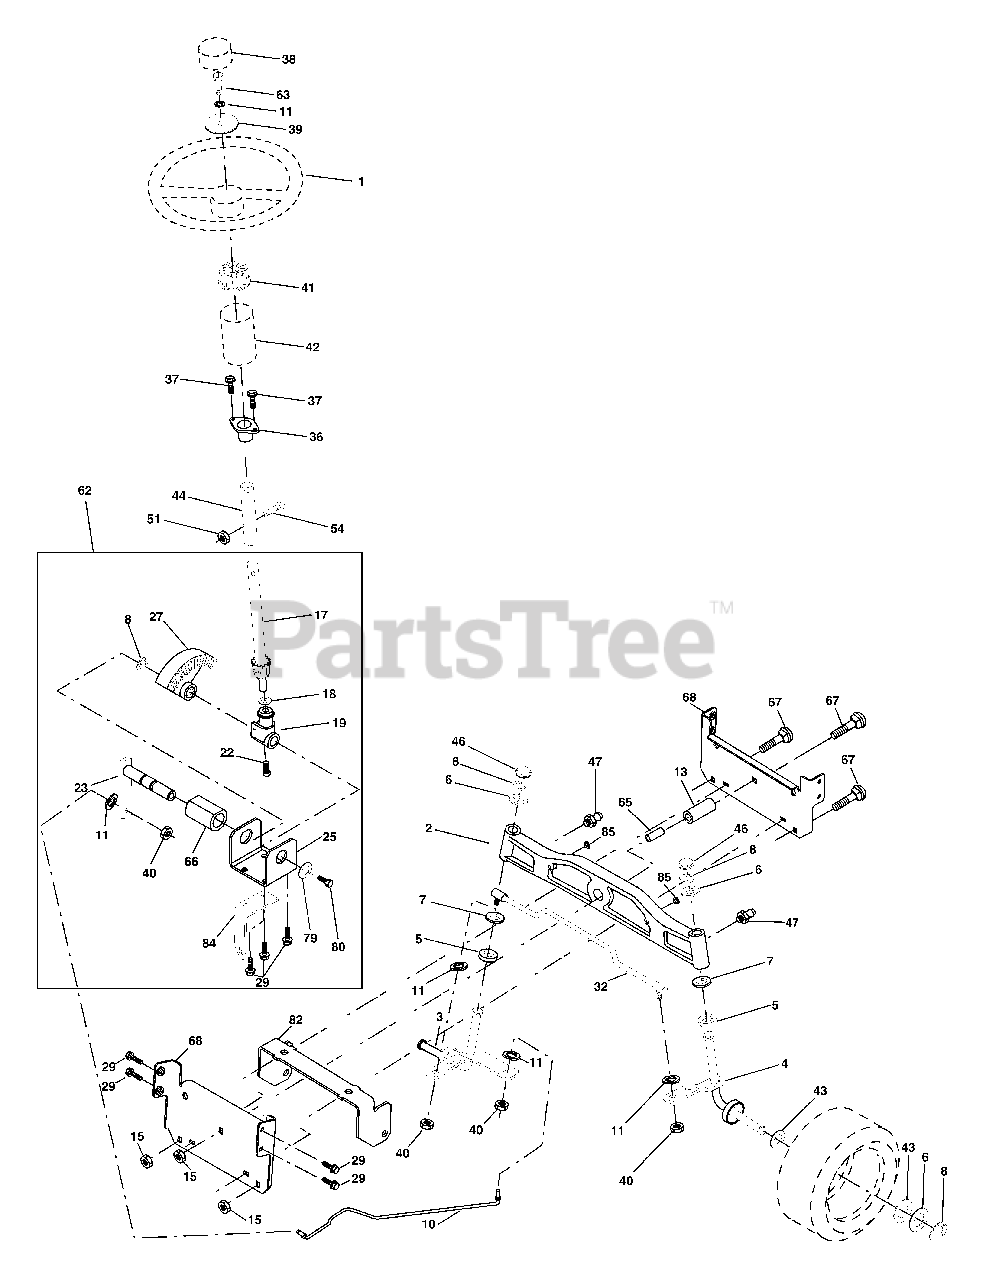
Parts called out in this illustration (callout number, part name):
1	Steering Wheel
2	Axle Cast Lt Machined
3	Spindle Assembly, L.H.
4	Spindle Assembly, R.H.
5	Bearing, Race, Thrust, Hardened
6	Washer 25/32 x 1-5/8 x 16 Gauge
7	Washer 27/32 x 1-1/4 x 16 Gauge
8	Ring, Klip
10	Link, Drag
11	Washer, Lock
13	Spacer Brg Axle Front
15	Nut Hex Flange Lock
17	Shaft Assembly, Steering
18	Washer, Thrust .515 x .750 x .033
19	Support, Shaft
22	Screw Hex Wshhd Torx
23	Pittman Shaft Assembly
25	Bracket, Steering
27	Gear, Sector
29	Screw 3/8-16 x 3/4
36	Bushing, Steering
37	Screw TT #I0-32 x 5 x 3/8 Flange
38	Cap Wheel Steering
39	Washer 13/32 x 1-1/20 x 11 Gauge
40	Nut Lock Center 3/8-24 Unf
41	Adaptor, Steering Wheel
42	Boot, Steering Dash P/L Mtl
43	Washer 25/32 x 1-1/4 x 16 Gauge
44	Extension Steering Non-Adjust
46	Cap, Spindle
47	Fitting, Grease
51	Nut Lock Hx W/Ins 5/16-18 UNC
54	Bolt Fin Hex 5/16-18 UNC x 1-1/4
62	Kit, Steering Assembly, Service
63	Bolt Fin Hex 3/8-16 unc. x 1 Gr. 5
65	Spacer Brace Axle
66	Bearing Arm Pittman
67	Bolt Rdhd Sqnk 3/8-16 x 2-1/4
68	Brace Axle
79	Washer 13/32 x 1-1/4 x 12 Ga
80	Bolt Hex Nylon 3/8-16 x 3/4
82	Bracket Susp Chassis Front
84	Bracket Cable Clutch Chassis
85	Fastner Christmas Tree
